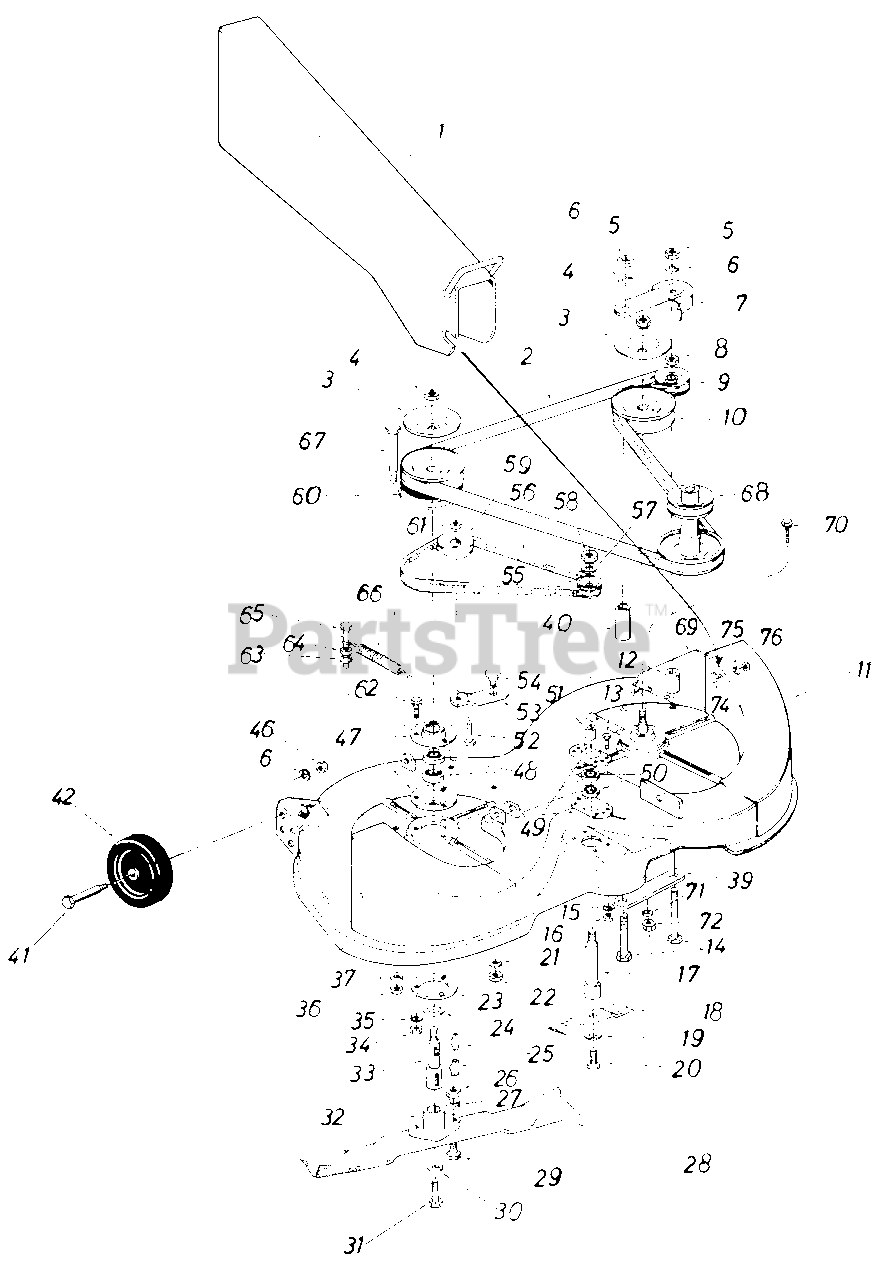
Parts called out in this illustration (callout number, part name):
1	Chute Extension Ass'y.-L.H.
2	"V"-Belt 1/2 x 84.0" Lg.
3	Brake Disc
4	Hex Cent. L-Nut 5/8-11 Thd.
5	Hex Jam Nut 3/8-16 Thd.*
6	L-Wash. 3/8" I.D.*
7	Idler Pulley Belt Guard Ass'y.
8	Hex Jam Nut 3/8-16 Thd.*
9	5/8-V Belt Idler 3.50" O.D.
10	5/8-V Pulley-.628" I.D. x 5.25" O.D.
11	40" Rear Discharge Deck
12	Spacer.40" I.D. x 1.25" O.D. x 1.59" Lg.
13	Hex Sems Bolt 1/4-28 x .62" Lg.
14	Hex Bolt 3/8-16 x 3.75" Lg.*
15	L-Wash. 1/4" I.D.*
16	Hex Nut 1/4-28 Thd.*
17	Blade Spindle
18	6.50" Blade
19	Bell-Wash. .40" I.D. x .88"O.D.
20	Hex Bolt 3/8-24 x .87" Lg.*
21	L-Wash. 3/8" I.D.*
22	Hex Nut 3/8-16 Thd.*
23	Plate-Deck Reinforcement
24	Bearing Shield
25	#6 Hi-Pro Key 5/32 x 5/8" Dia.
26	Hex Nut 5/16-24 Thd.*
27	L-Wash. 5/16" I.D.*
28	20" High Lift Blade-R.H.
29	Hex Bolt 5/16-24 x 1.00" Lg. (Grade 5)
30	L-Wash. 3/8" I.D. Heavy Duty
31	Hex Bolt 3/8-24 x 1.50" Lg. (Grade 5)
32	Blade Adapter Kit
33	Blade Spindle
34	Hex Nut 5/16-18 Thd.*
35	L-Wash. 5/16" I.D.*
36	Hex Nut 3/8-16 Thd.*
37	L-Wash. 3/8" I.D.*
39	Reinforcement Plate
40	Spacer 3/8" I.D. x .50" O.D. x 2.72"
41	Shld. Bolt .498" Dia. x 1.53" Lg.
42	Cutting Deck Wheel
46	Hex Jam Nut 3/8-16 Thd.
47	Bearing Housing
48	Ball Bearing .787" I.D. x 1.85" O.D.
49	Bearing Housing
50	Ball Bearing .63" I.D. x 1.38" O.D.
51	Spacer.63" I.D. x .88" O.D. x 1.25" Lg.
52	Hex Bolt 3/8-16 x 1.25" Lg.
53	Idler Bracket
54	Shld. Bolt .625" Dia. x .170" Lg.
55	3/8" V-Pulley .628" I.D. x 2.00" O.D.
56	"V"-Belt 3/8 x 39.0" Lg.
57	Bell-Wash. .63" I.D. x 1.05" O.D.
58	Hex Jam Nut 5/8-11 Thd.*
59	1/2" V-Belt Idler 2.625" O.D.
60	Double Pulley
61	Hex Top L-Jam Nut 3/8-16 Thd.
62	Hex Sems Bolt 5/16-18 x 1.00" Lg.
63	L-Wash. 1/4" I.D.
64	Hex Nut 1/4-20 Thd.
65	Hex Bolt 1/4-20 x 1.00" Lg.
66	Ext. Spring .50" O.D. x 3.97" Lg.
67	Shld. Bolt .498" Dia. x 2.63" Lg.
68	Two Step Engine Pulley
69	Inner Chute Extension-L.H.
70	Hex Sems Scr. 1/4-28 x .62" Lg.
71	L-Wash. 1/4" I.D.
72	Hex Nut 1/4-28 Thd.
74	Shld. Scr. .500" Dia. x .218
75	L-Wash. 3/8" I.D.
76	Hex Jam Nut 3/8-16 Thd.
